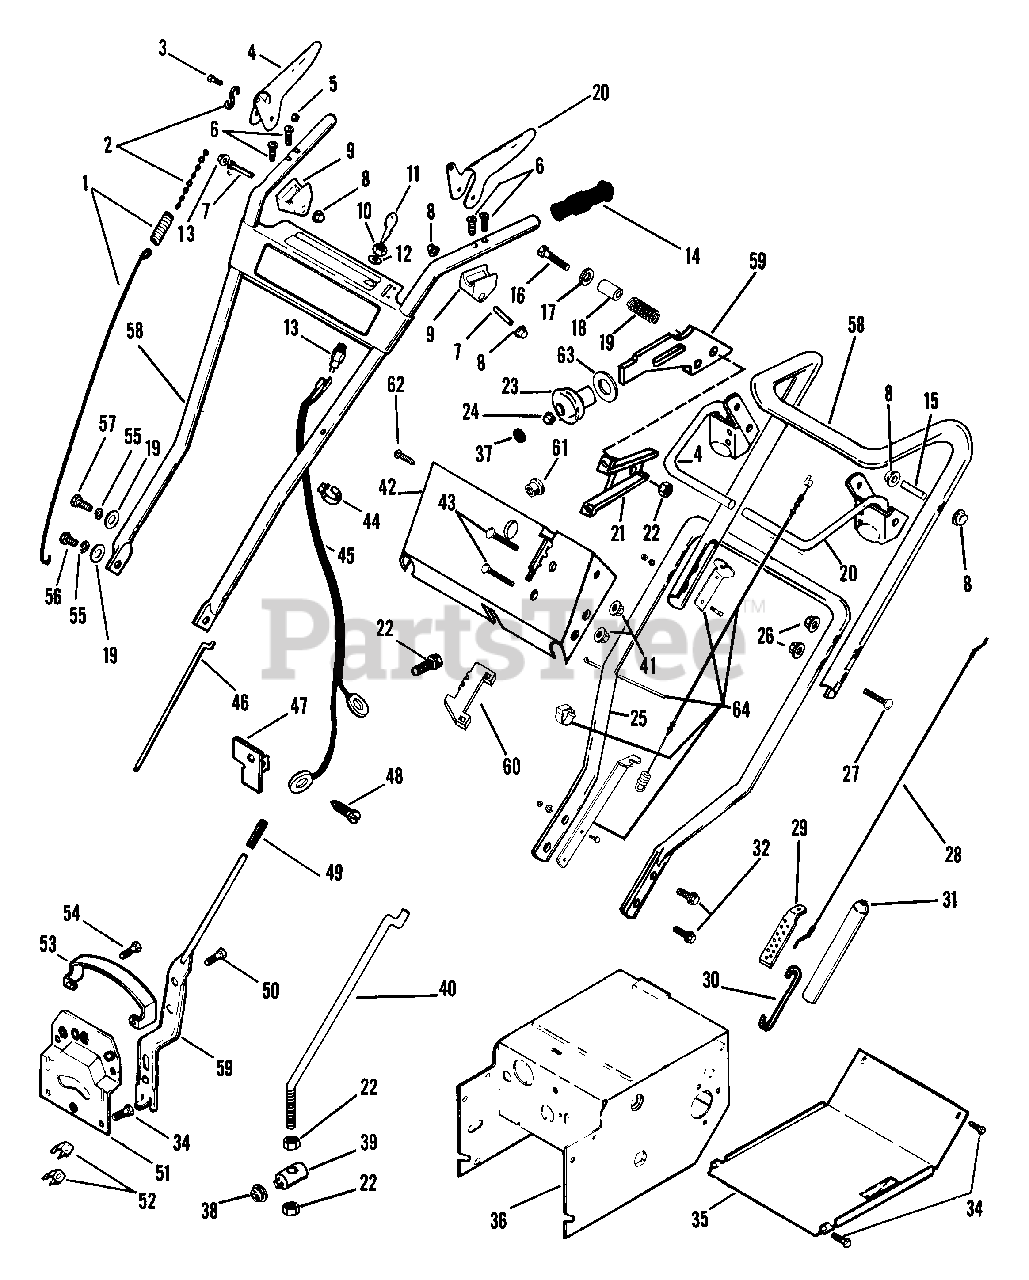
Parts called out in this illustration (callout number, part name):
1	SG-TENS .080X.25X31.6 WLD 35
2	CHAIN & CONNECTOR
3	BLT-HEX .25-20X.50 PL GR2
4	RH LEVER
4	ATTACHMENT CLUTCH HANDLE
5	NUT-LK-CTR .250-20 PL
6	SCR-TAP 12-14X1.50 CROVH PL BT
8	PUSH NUT, .25
9	HANDLE PIVOT
10	NUT .625-32 ALUM
11	KEYS
12	WSHR-LK-INT .625X.045 PL
13	KEY SWITCH ASSEMBLY
13	SWITCH
14	GRIP
15	PIN
16	BLT-HEX .31-18X2.00 PL GR2
17	WSHR-FL-STL .328X1.0X.094 PL
18	SPACER -SPLIT .340X.490X1.02
19	SG-COMP .105X1.0X2.25 WLD 50
20	TRACTION CLUTCH HANDLE WITH DE
20	LH LEVER
21	SHIFT PIVOT
22	NUT-LK .312-18 GR A PL
23	GRIP
24	NUT-PUSH .38 DIA. PAL ZINC
25	LOWER HANDLEBAR
26	NUT-FLG. .312-18 PL
27	BLT-RDHDSQNK .31-18X1.50 PL BL
28	CABLE
29	ADJUSTMENT PLATE
30	LINK
31	COVER
32	BLT-SERHFWH .31-18X.62 PL
34	SCR-TAP .250-20X.37 HWH PL TR
35	BOTTOM COVER
36	FRAME
36	FRAME ASSEMBLY
37	HOLE PLUG
38	CAP, 3/8 ROD YWZC
39	SWIVEL
40	SHIFT ROD
41	NUT-FLG. .312-18 PL
42	HANDLEBAR PANEL 3.5
42	HANDLEBAR PANEL 5.0
42	HANDLEBAR PANEL ST724
42	HANDLEBAR PANEL ST420
43	BLT-RDHDSQNK.31-18X.50 SHTPLBL
44	CONDUIT CLAMP 2 WIRE
45	SHORTING WIRE
45	WIRE
46	CLUTCH ROD
47	REMOTE STOP TERMINAL BLOCK
48	SCR-TAP 8-15X.38 CR RH A
49	GRIP - 5/16 ID X 2 7/8 - BLACK
50	SCR-TAP 10-24X.50 CRSLPH PL 1A
51	QUADRANT
52	NUT-RETNR .312-18 TINRMAN
53	SHIFT HANDLE RETAINER
54	SCR-TAP 10-24X.375 HWH PL TR
55	WSHR-LK .312X.097 PL HVY
56	BLT-HEX .31-18X.75 PL GR2
57	BLT-HEX .31-18X1.50 PL GR2
58	HANDLEBAR WELDMENT
58	UPPER HANDLEBAR W/BUSH & DECAL
59	SHIFT HANDLE
60	QUADRANT DOUBLER
61	BSHG-FLG .439X.501X.144X.625NY
62	SCR-TAP 10-24X.375 TORX PHD
63	WSHR-FL-STL .382X.812X.023 PL
64	BLOWER CABLE W/BRACKETS
64	UPPER CABLE MOUNT
64	LOWER CABLE MOUNT
64	CLUTCH CABLE
64	BLT-HEX .25-20X1.25 PL GR5
64	NUT-LK-CTR .250-20 PL
64	CONDUIT CLAMP 2 WIRE
64	CABLE TIE LG 5-1/2
64	BLT-HEX .31-18X1.00 PL GR5
64	WSHR-LK .313X.062
